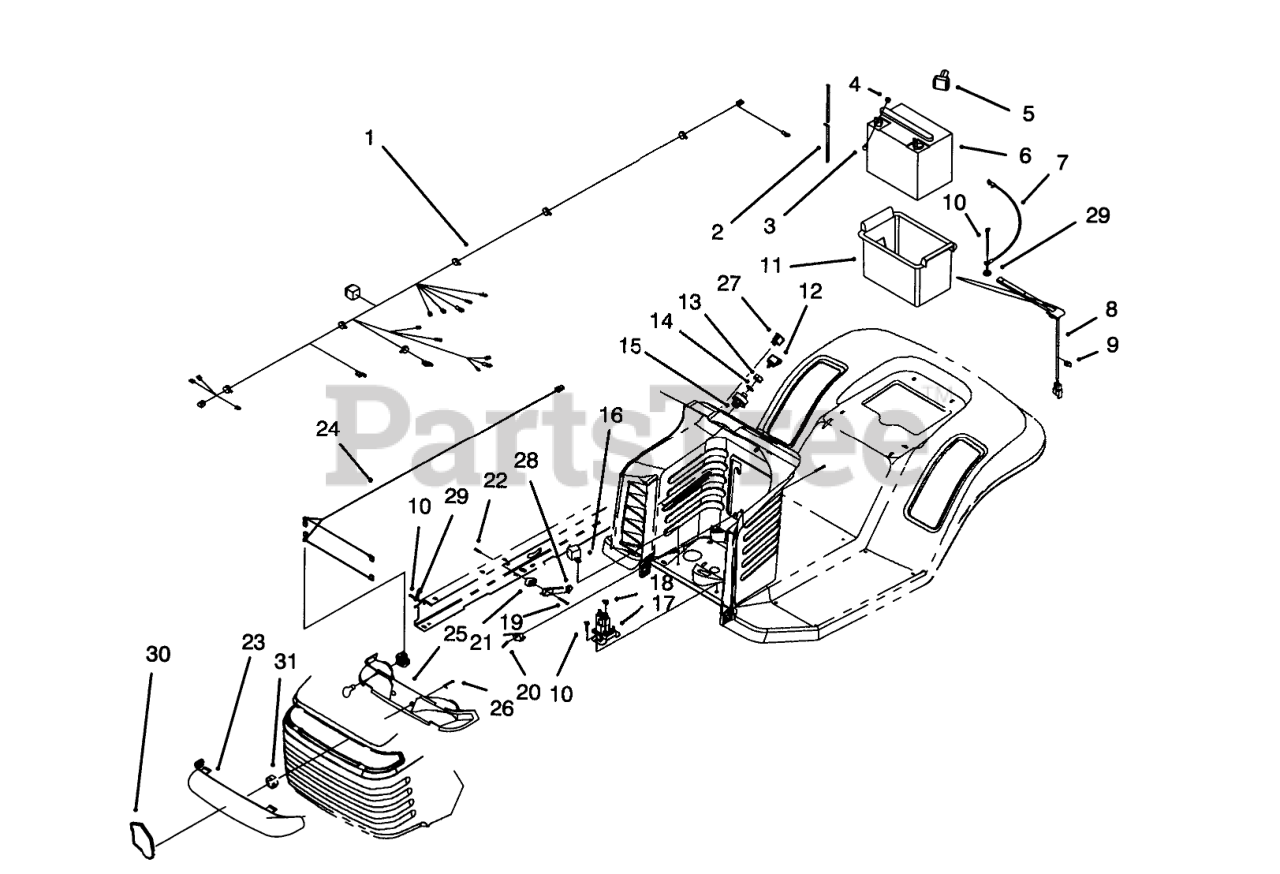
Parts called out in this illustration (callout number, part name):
1	Harness-Wire
2	TUBE-BATT DRAIN/80-2600
3	SCREW-HH
4	NUT-WING
5	BOOT-TERMINAL
6	Battery
7	WIRE ASM
8	SWITCH-SEAT
9	CLIP-RETAINER, WIRE
10	SCREW-HWH
11	BOX-BATTERY
12	KEY-IGNITION
13	NUT-HH
14	WASHER-TOOTH, INTERNAL
15	Switch-Ignition (Incl. Ref. #13 & 14)
16	RELAY
17	SOLENOID
18	NUT-KEPS
19	Screw
20	SWITCH-MICRO
21	SPACER
22	NUT-SPEED
23	LENS-HEADLIGHT
24	HARNESS-WIRE, LIGHTS
25	HEADLIGHT REFLECTOR ASM
27	MICROSWITCH ROCKER SWCH
28	Seal-Plunger
29	WASHER-LOCK/EXT
30	EMBLEM-GRILLE WHEELHORSE
